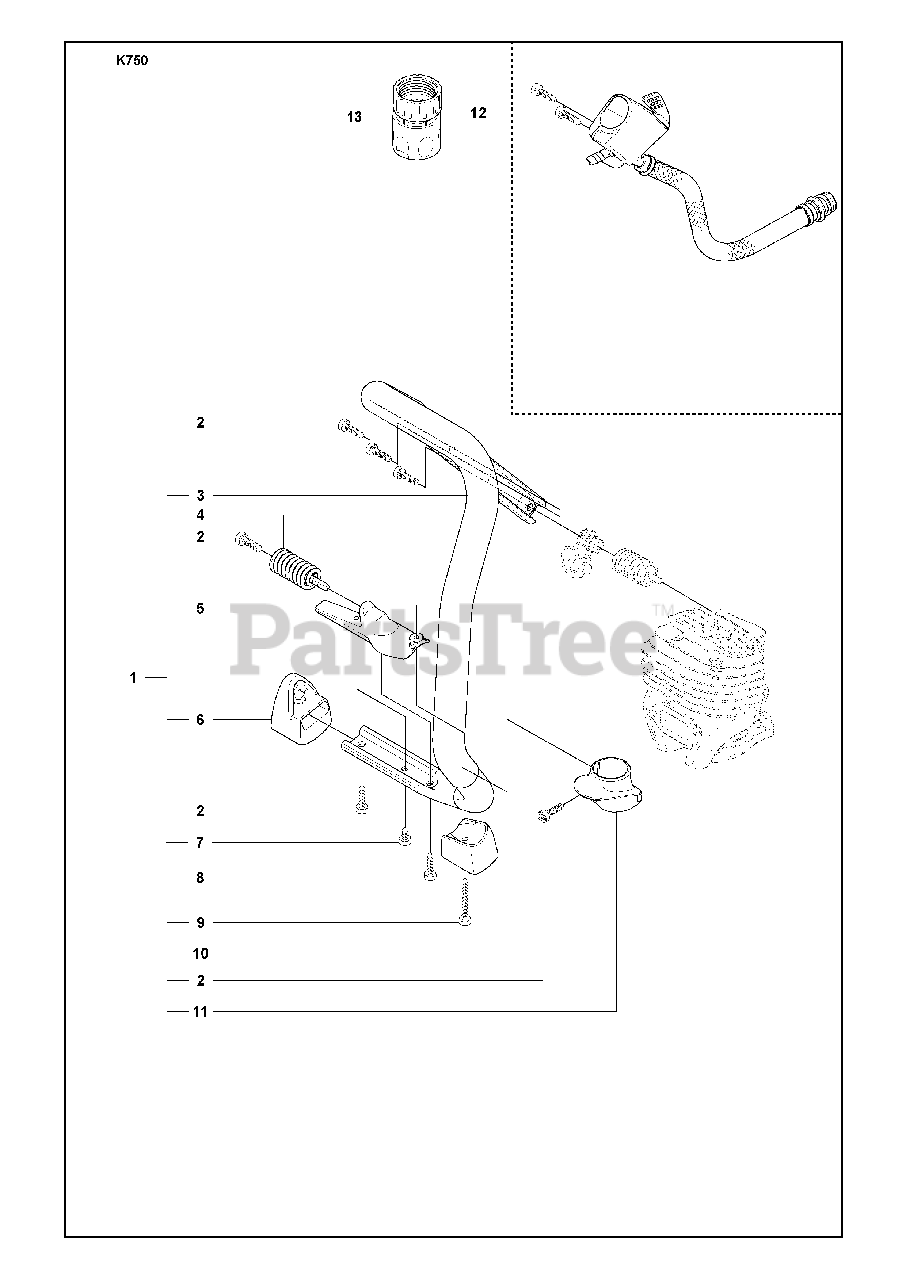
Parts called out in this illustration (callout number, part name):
1	HANDLE
3	FRONT HANDLE
4	AV-ELEMENT
5	SPRING RETAINER
6	GROUND SUPPORT
10	GROUND SUPPORT
12	HOSE
13	COUPLER
